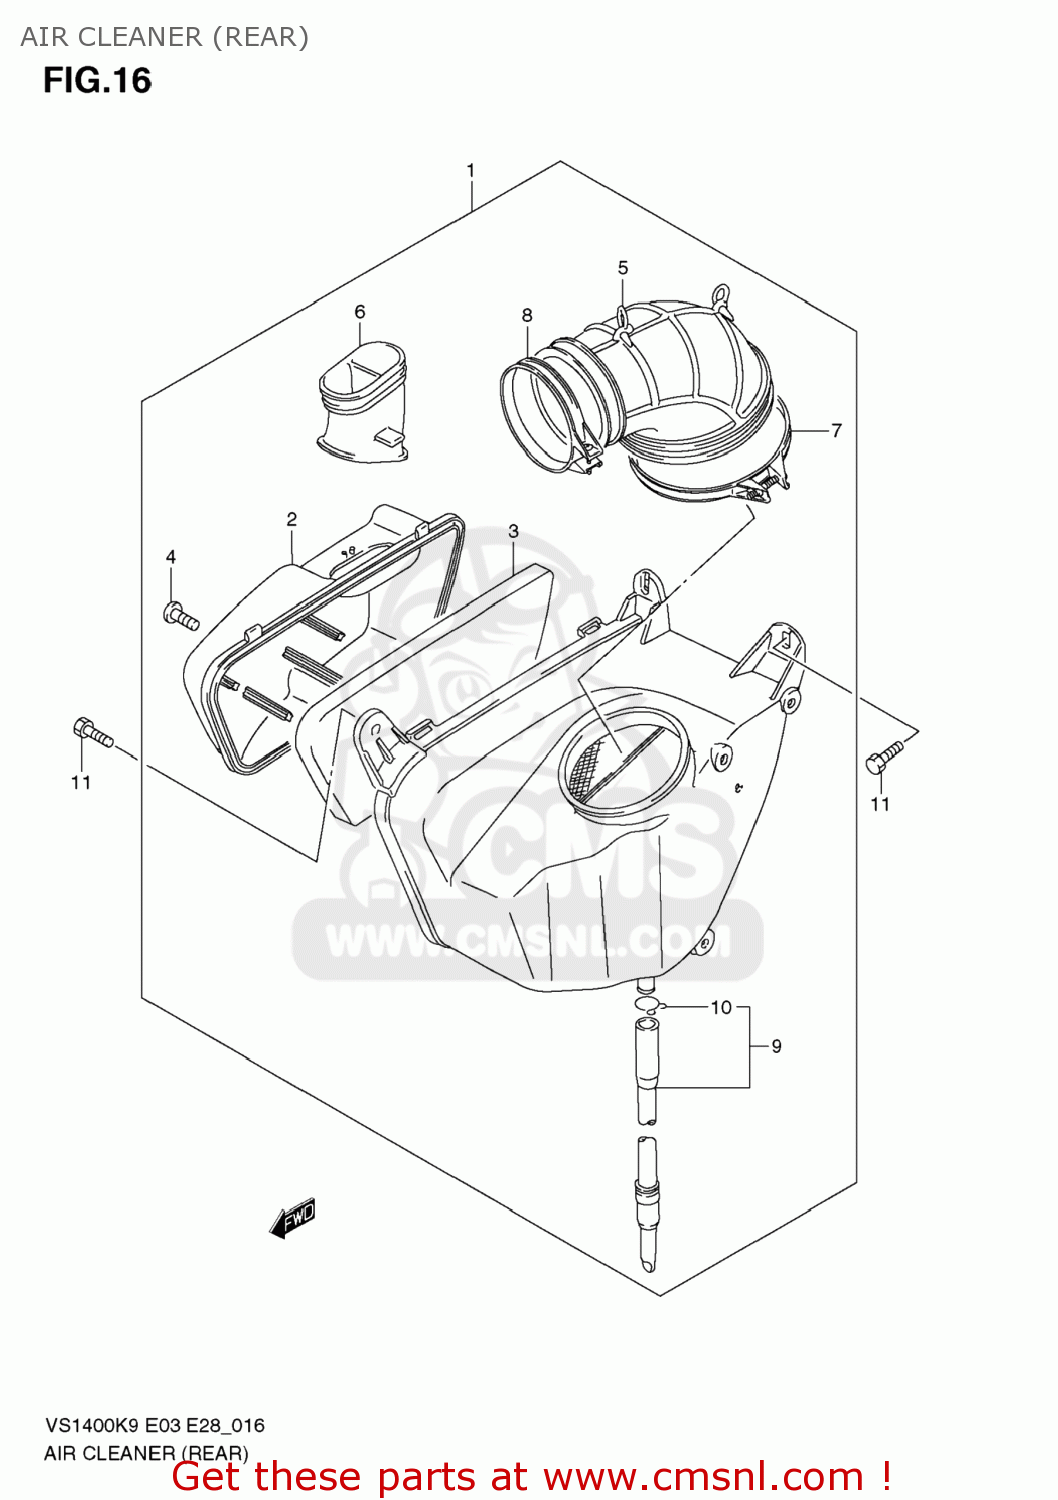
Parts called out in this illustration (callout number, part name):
1	CLEANER ASSY,AIR RR
2	CAP,AIR CLEANER RR
3	FILTER,AIR RR
4	SCREW
5	TUBE,AIR CLEANER OUTLET
6	TUBE,INLET
7	CLAMP
8	CLAMP
9	TUBE,DRAIN
10	CLIP
11	BOLT
